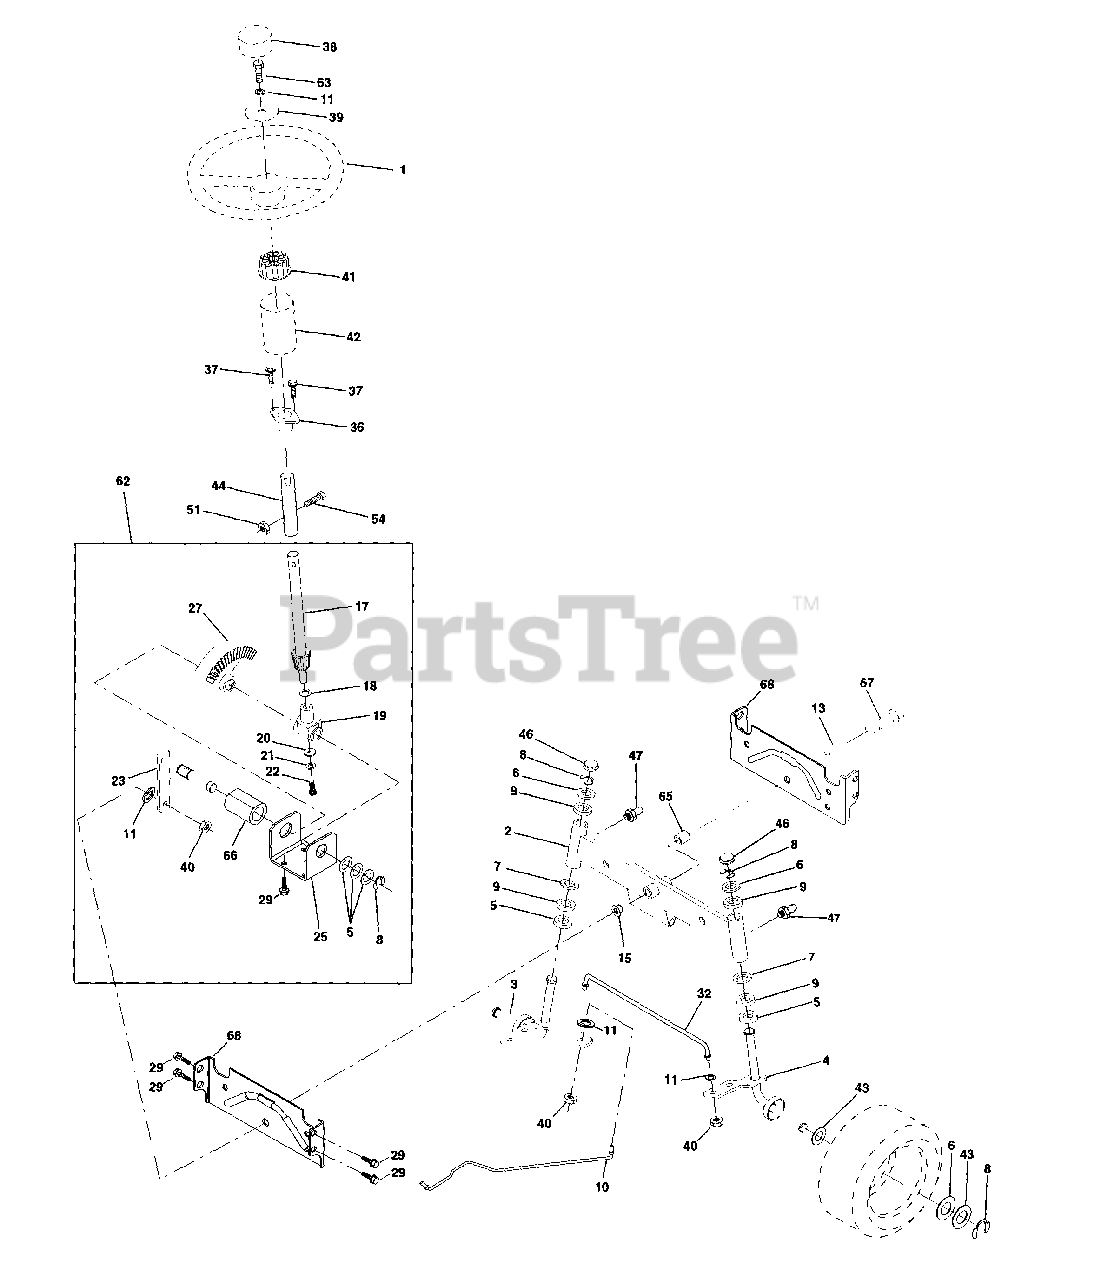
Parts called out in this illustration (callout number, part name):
1	Wheel Steering
2	Axle Front Casting Machined
3	Spindle Asm LH
4	Spindle Asm RH
5	Bearing Race Thrust Harden
6	Washer 25/32 X 1-5/8 X 16 Ga
7	Washer 27/32 X 1-1/4 X 16 Ga
8	Ring Klip #t5304-75
9	Bearing Col Strg Blk
10	Link Drag Extended Cast
11	Washer Lock Hvy Hlcl Spr 3/8
13	Bearing Axle STLT/GT
15	Nut Lock Flange 5/8-11 Unc
17	Shaft Asm Strg
18	Washer Thrust 515 x 750 x 033
19	Support Shaft
20	Washer Shim 1/4 x 5/8 x 062
21	Washer Lock Hvy Helical 1/4
22	Screw Cap Sckt Hd Phos & Oil
23	Shaft Asm Pittman
25	Bracket Steering
26	Bushing Link Drag Blk LR
27	Gear Sector
28	Washer 13/32 x 7/8 x 16 Ga
29	Screw Thdrol 3/8-16 x 3/4 Ty-tt
30	Pin Cotter 1/8 X 3/4 Cad
32	Rod Asm Tie Ball
36	Bushing Strg
38	Insert Cap Strg Wh Au
39	Washer 13/32 X 2-3/8 X 8 Ga
40	Lock nut
41	Adaptor Wheel Strg
42	Boot Steering Shaft
43	Washer 25/32 X 1-1/4 X 16 Ga
44	Extension Steering Shaft LR/LT
46	Cap Spindle Fr Top Blk
47	Fitting Grease
51	Nut Lock Hex w/Ins 5/16-18
54	Bolt Fin Hex 5/16-18 Unc x 1-1/4
62	Kit, Steering Assembly Svc
63	Bolt Fin Hex 3/8-16unc x 1 Gr. 5
65	Spacer Axle
66	Bearing Arm Pittman
67	Bolt, Fin Hex 5/8-11 UNC x 2-3/4
68	Axle, Brace
